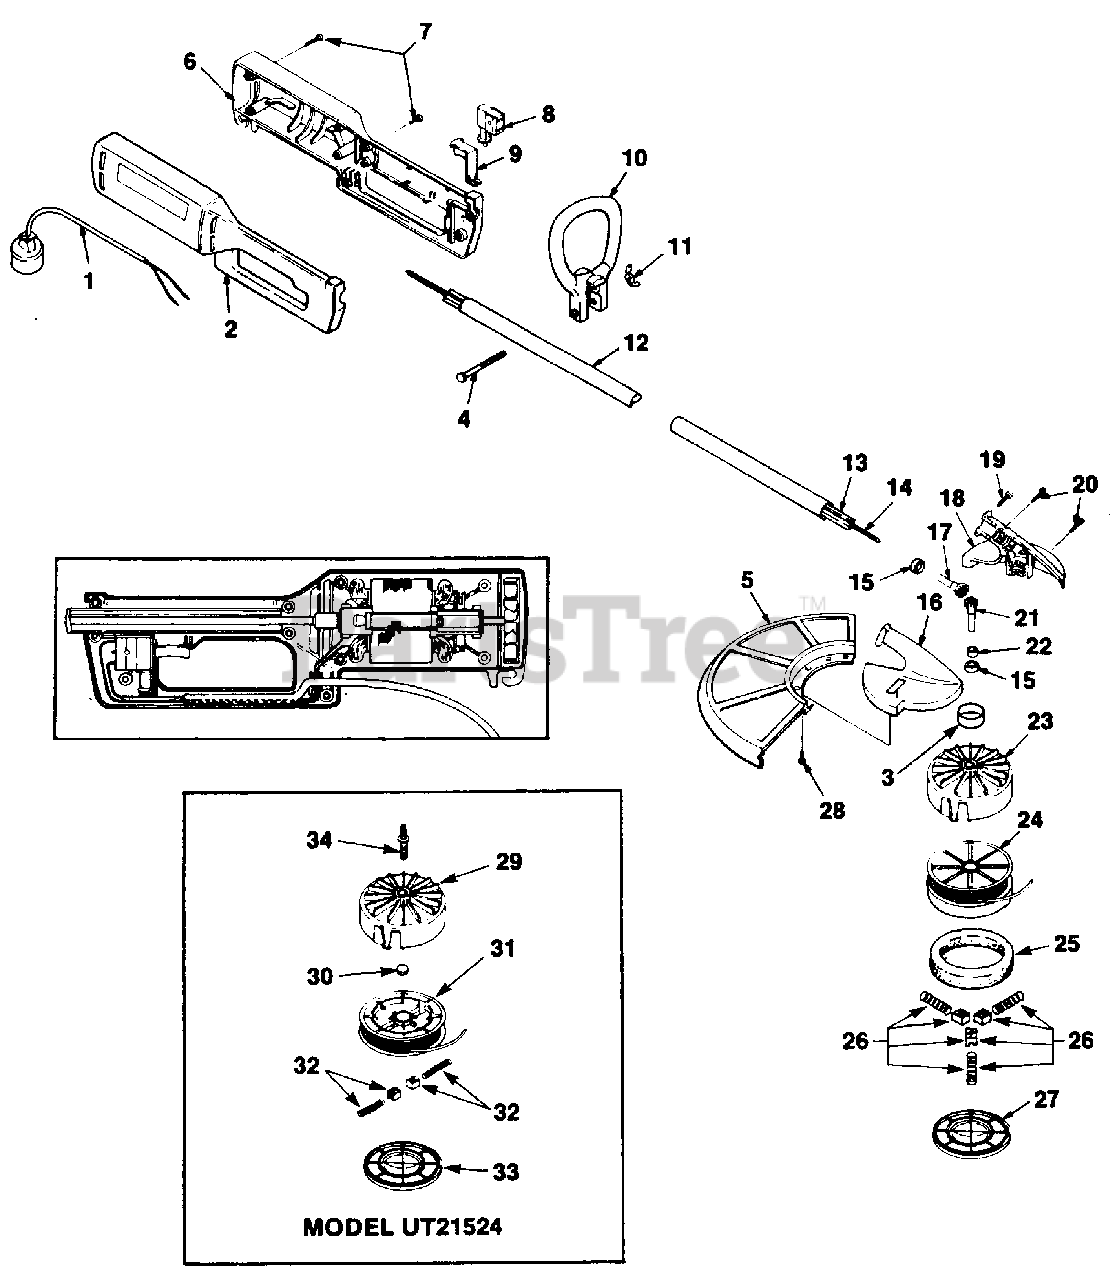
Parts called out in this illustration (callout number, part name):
1	CORD SET
2	HOUSING- Motor (right)
3	WASHER- Cupped (UT21524-A)
4	SCREW- Hex hd. (1/4-20 x 2")
5	STRING GUARD w/Cut-off blade
6	HOUSING- Motor (left)
7	SCREW- Thd. forming (#10-16 x 9/16")
8	SWITCH
9	TRIGGER- Switch
10	HANDLE- Front
11	NUT- Wing
13	TUBE- Liner
14	SHAFT- Flexible
15	BEARING
16	HOUSING- Gear (right)
17	GEAR- Drive
18	HOUSING- Gear (left)
19	SCREW- Thd. forming (10-16 x 3/4")
20	SCREW- Thd. forming (6-19 x 3/4")
21	GEAR- Driven
22	BEARING- Flange
23	STRINGHEAD & EYELET ASSY. (UT21524-A)
24	SPOOL & STRING (UT21524-A)
25	RING- Foam (UT21524-A)
26	SLIDE & SPRING KIT (UT21524-A)
27	RETAINER- Spool (UT21524-A)
28	SCREW- Thd. forming (#10-14 x 5/8")
29	STRINGHEAD EYELET ASSY. (UT21524)
30	BUMPER- Rubber (UT21524)
31	SPOOL & STRING (UT21524)
32	SLIDE & SPRING KIT (UT21524)
33	RETAINER- Spool (UT21524)
34	CONNECTOR- Drive (UT21524)
